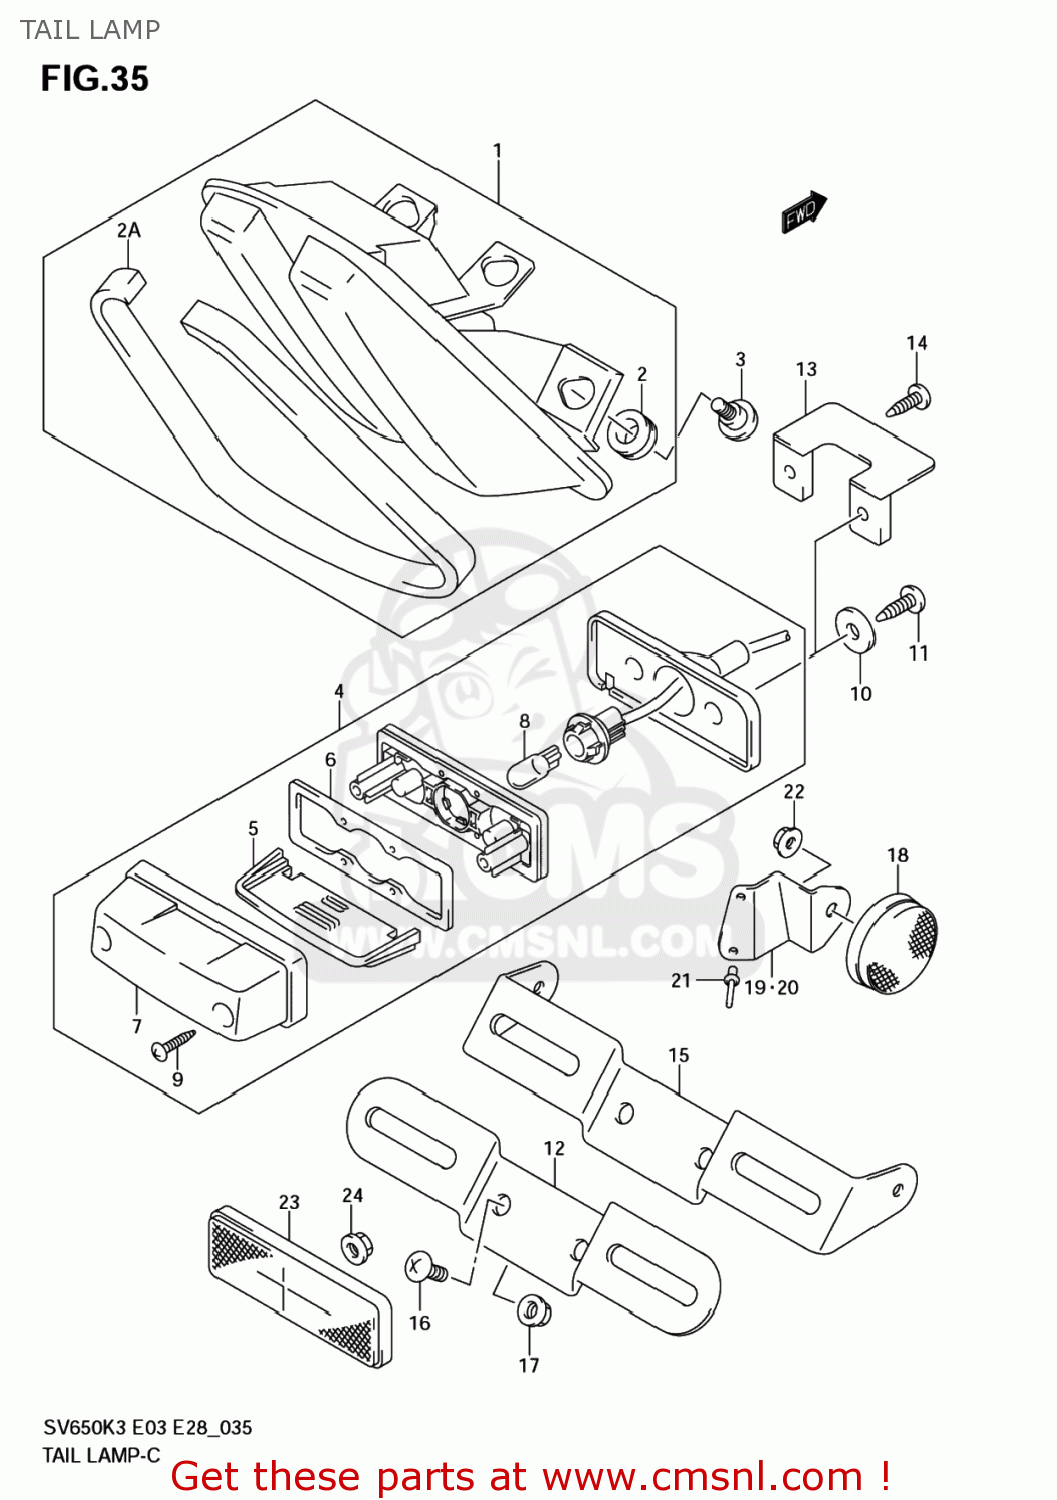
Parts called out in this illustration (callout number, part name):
1	LAMP ASSY,RR COMBINATION
2	CUSHION
2A	CUSHION,SEAT TAIL COVER
3	SCREW(6X22.5)
4	LAMP ASSY,LICENSE
5	LENS
6	GASKET (NAS)
7	COVER
8	BULB(12V5W)
9	SCREW
10	WASHER(5.5X20X1.2)
11	SCREW
12	BRACKET,LICENSE PLATE
13	BRACKET,LICENSE
14	SCREW
15	BRACKET,LICENSE PLATE
16	SCREW
17	NUT
18	REFLECTOR ASSY,RR SIDE
19	BRACKET,RR SIDE RR,R
20	BRACKET,RR SIDE RR,L
21	RIVET
22	NUT
23	REFLECTOR ASSEMBLY,REAR
24	NUT
